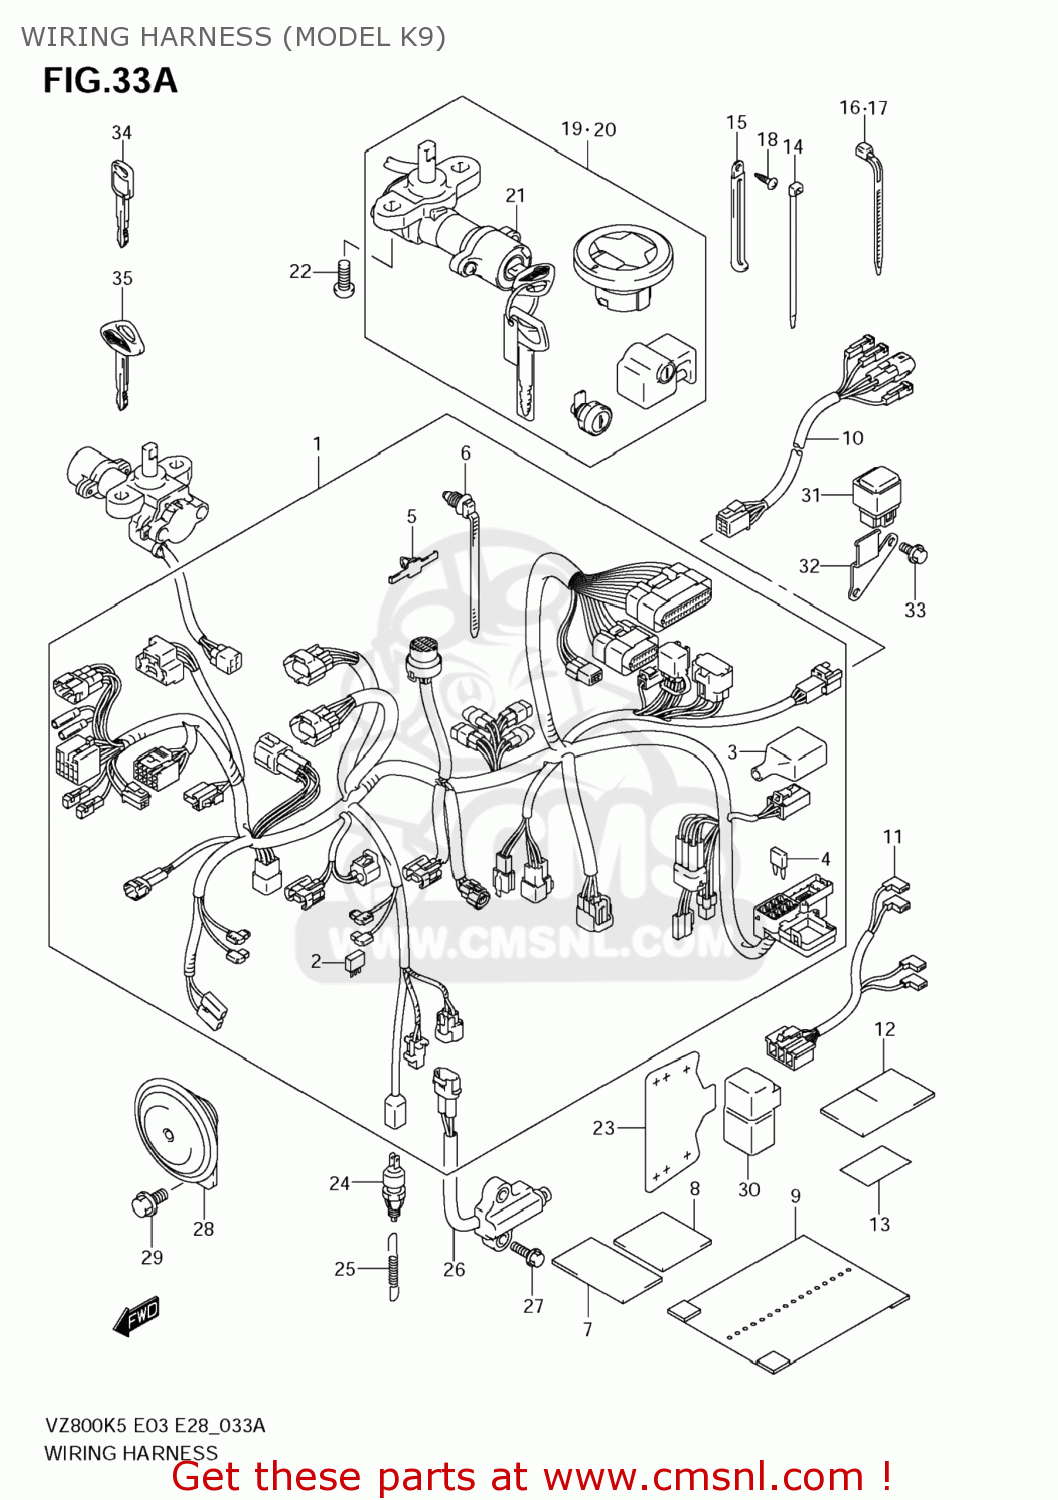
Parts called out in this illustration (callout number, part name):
1	HARNESS,WIRING
2	DIODE(STANLEY DE8804)
3	BOOT
4	FUSE(10A)
5	CLAMP
6	CLAMP(L:154)
7	TAPE,WIRING HARNESS(28X50X0.13
8	PROTECTOR,WIRING HARNESS
9	COVER,WIRING HARNESS
10	WIRE,REAR COMB
11	WIRE,IGNITION COIL LEAD
12	PROTECTOR,HARNESS(30X50X3)
13	PROTECTOR,COWLING UNDER
14	CLAMP(L:145)
15	CLAMP(L:80)
16	CLAMP(L:165)
17	CLAMP(L:190)
18	SCREW
19	LOCK SET
20	LOCK SET
21	LOCK ASSY,STEERING
22	BOLT(8X20)
23	PROTECTOR,IGNITION SWITCH
24	SWITCH ASSY,STOP LAMP
25	SPRING
26	SWITCH ASSY,SIDE STAND
27	BOLT(6X20)
28	HORN ASSY
29	BOLT
30	RELAY ASSY
31	RELAY ASSY
32	BRACKET,HEADLAMP RELAY
33	BOLT
34	KEY,BLANK
35	KEY,BLANK(BOULEVARD)
